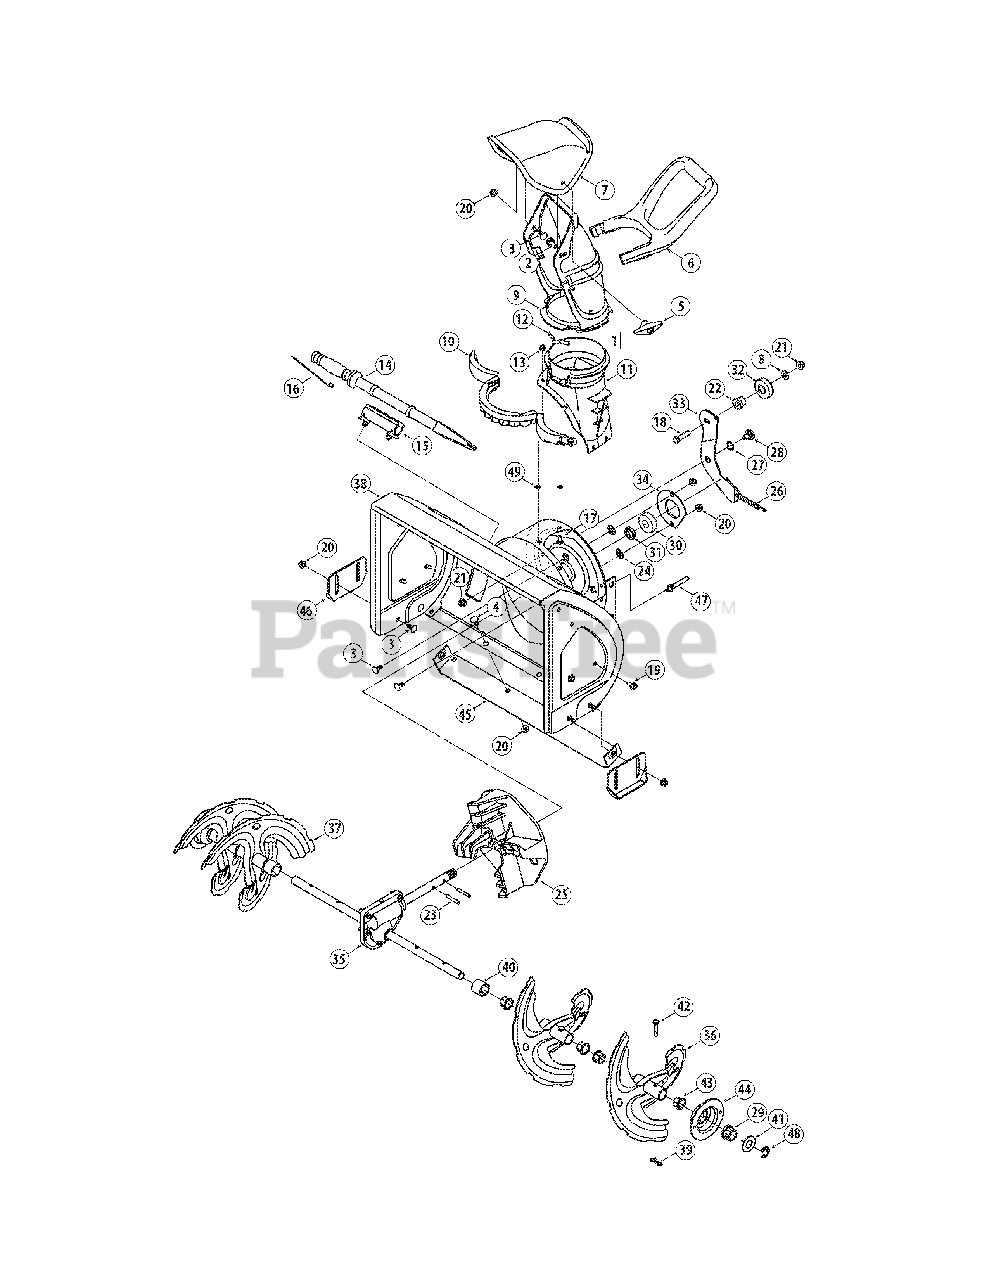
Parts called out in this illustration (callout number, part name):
1	Chute Assembly
2	Carriage Bolt 5/16-18 x 1.0"
3	Carriage Bolt 5/16-18
4	Carriage Bolt 5/16-18 x .62
5	Wing Knob 5/16-18
6	Chute Handle
7	Upper Chute
8	Flat Washer .385 x .87 x .06
9	Lower Chute
10	Chute Ring
11	Chute Adapter 5" Dia.
12	Chute Adjustment Spring
13	Flange Lock Nut 1/4-20
14	Clean-out Tool
15	Clean-out Tool Mount
16	Cable Tie
17	Carriage Screw 1/4-20 x 0.62"
18	Hex Bolt 3/8-16 x 1.50"
19	AB Screw 5/16-18 x .750
20	Flange Lock Nut, 5/16-18
21	Flange Lock Nut, 3/8-16
22	Shoulder Spacer
23	Spiral Pin
24	Push On Nut
25	Impeller
26	Extension Spring
27	Wave Washer
28	Shoulder Screw 3/8-16
29	Hex Flange Bearing
30	Ball Bearing
31	Spacer
32	Flat Idler
33	Auger Idler Bracket
34	Bearing Housing
35	Auger Gearbox Assembly
36	Auger Assembly - LH
37	Auger Assembly - RH
38	Auger Housing, 22"
39	Bow Tie Cotter Pin 72
40	Spacer, 1.25 x.75 x 1.00
41	Flat Washer, .76 x 1.49 x .06
42	Shear Pin,.25 x 1.50
43	Flange Bushing
44	Hex Bearing Housing
45	Shave Plate 2.25 x 21.66 LG
46	Skid Shoe
47	Belt Keeper
48	E-Ring, .750
49	Push Nut
